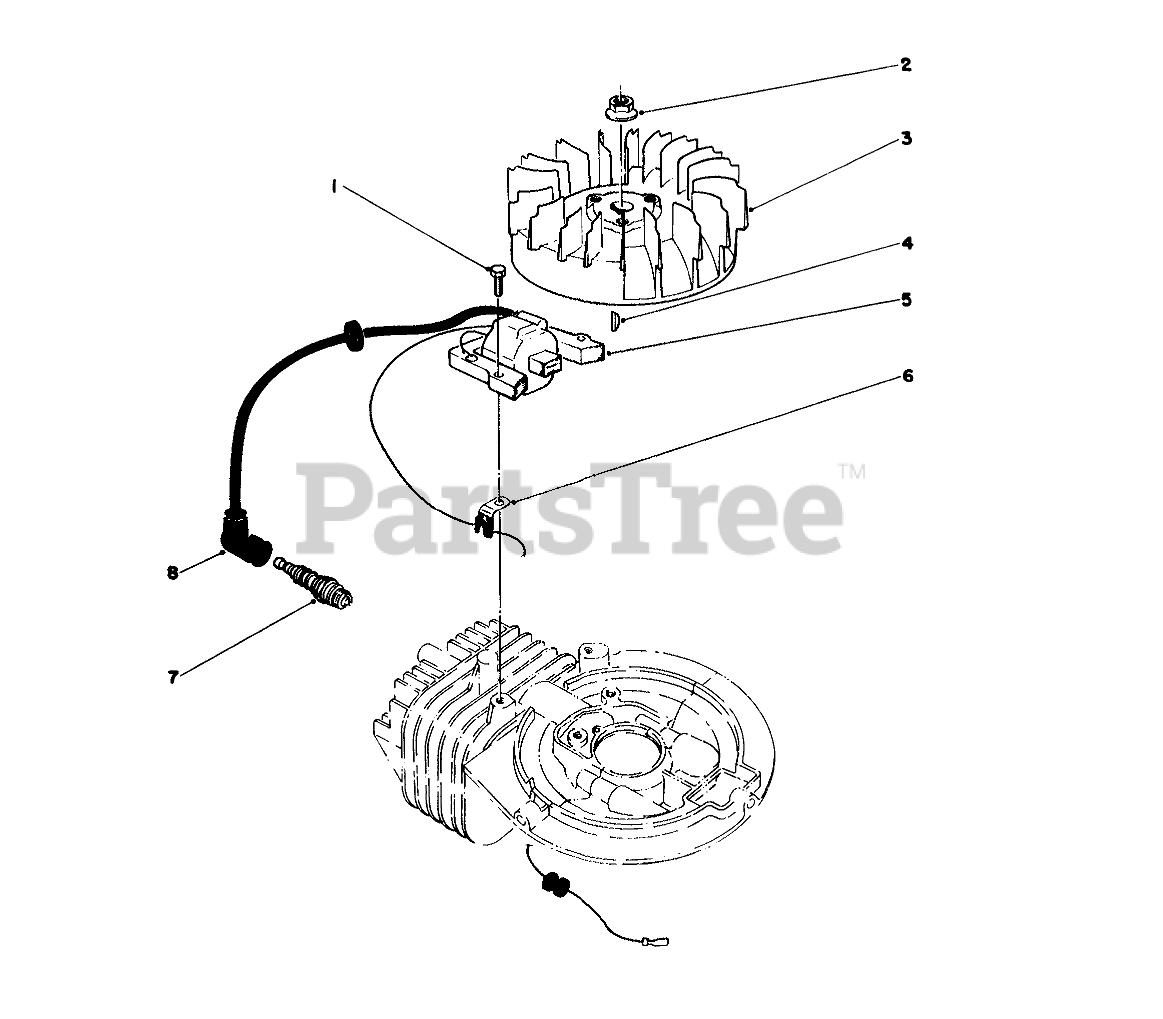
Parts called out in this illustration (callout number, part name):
1	SCREW
3	FLYWHEEL
5	COIL-MAGNETO
6	CLAMP
7	Sparkplug
8	110 Nut
